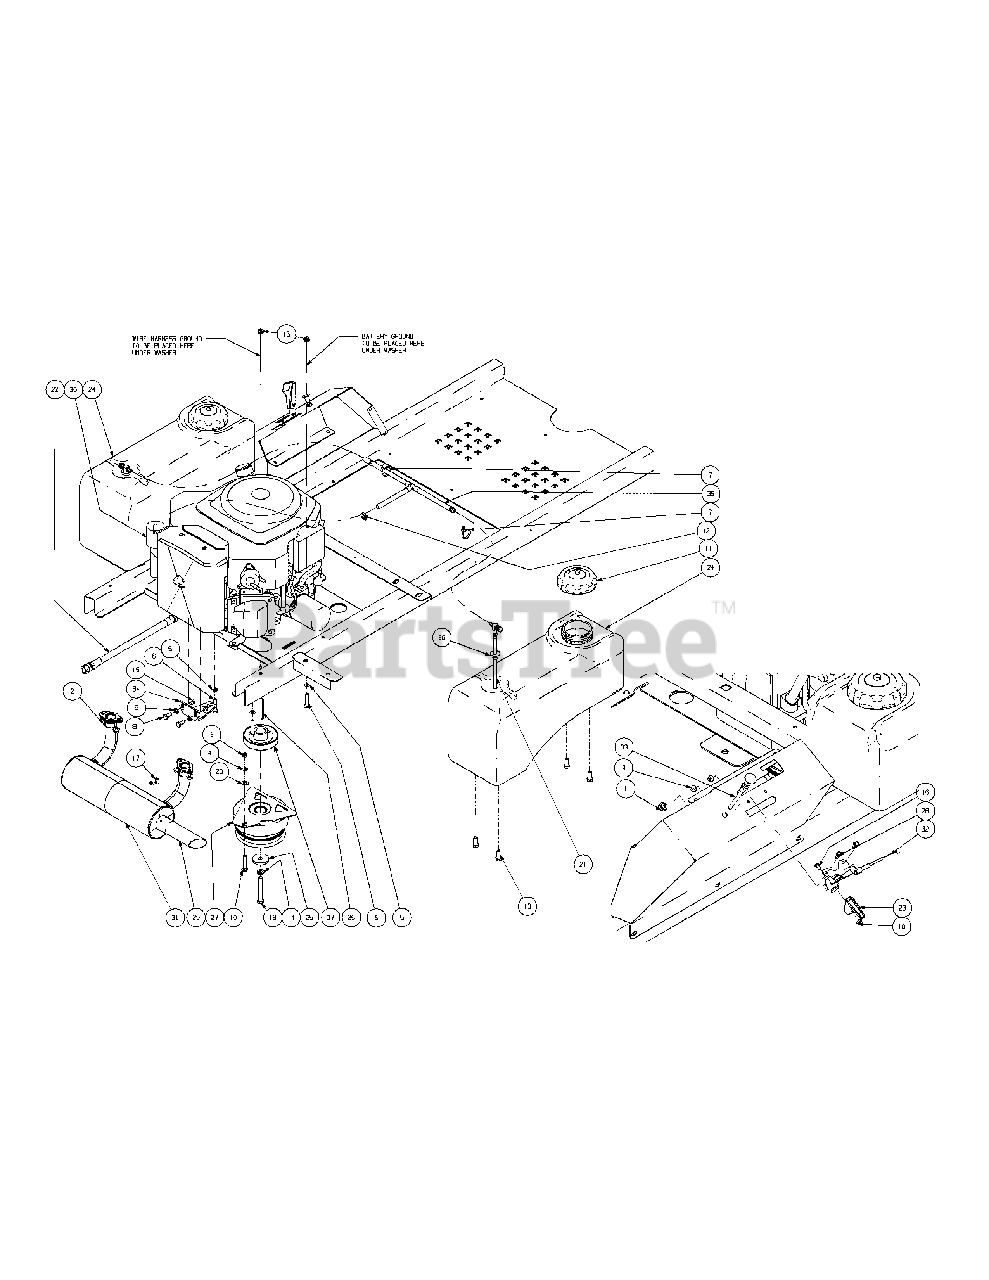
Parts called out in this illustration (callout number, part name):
1	Jam Nut, 3/8-24
2	Nut, M8-1.25, Hex Flange
3	Hex Nut, 5/16-18
4	Lock Washer, 5/16
5	Flat Washer, 5/16
6	HHCS, 5/16-18, 1-1/2
7	Cable Tie, 3/16 x .05 x 7.4
8	Hex Cap Screw, 5/16-18 x .75
9	Lock Nut, Nylon Insert, 10-32
10	Nut, w/ Star Washer
12	Hose Clamp, SAE #4: 1/4-5/8, SS
13	HHCS, 3/8-16 x .500, Flange Whiz
14	Lock Washer, 7/16
15	Lock Nut, Hex Flange, 5/16-18
16	Machine Screw, 8-32 x .375
17	Screw, 8-32 x .375, Hex Washer
18	Hex Cap Screw, 7/16-20 x 3.0
19	Carriage Bolt, 5/16-18 x 1.75
20	Washer, 3/8 x .738 x .063
21	Fuel Pickup Fitting
22	Oil Drain Extension Hose
23	Throttle Control Knob
24	Fuel Tank
25	Flat Washer, 7/16 ID x 1.75 OD x .250
26	Key, 1/4 x 1/4 x 2.75
27	Ogura DX11 Electric Clutch
28	Screw, #10-32 x 0.500
29	Exhaust Pipe
30	23HP Kohler Engine
31	Muffler, Silexsys
32	Throttle Control Cable
33	Choke Cable
35	Fuel Hose Assembly includes:
35	Hose, 1/4" Fuel Line (70 inches)
35	Clamp, Union
35	Tee Fitting, Fuel
36	Fuel Tank Groment
37	Transmission Drive Pulley
